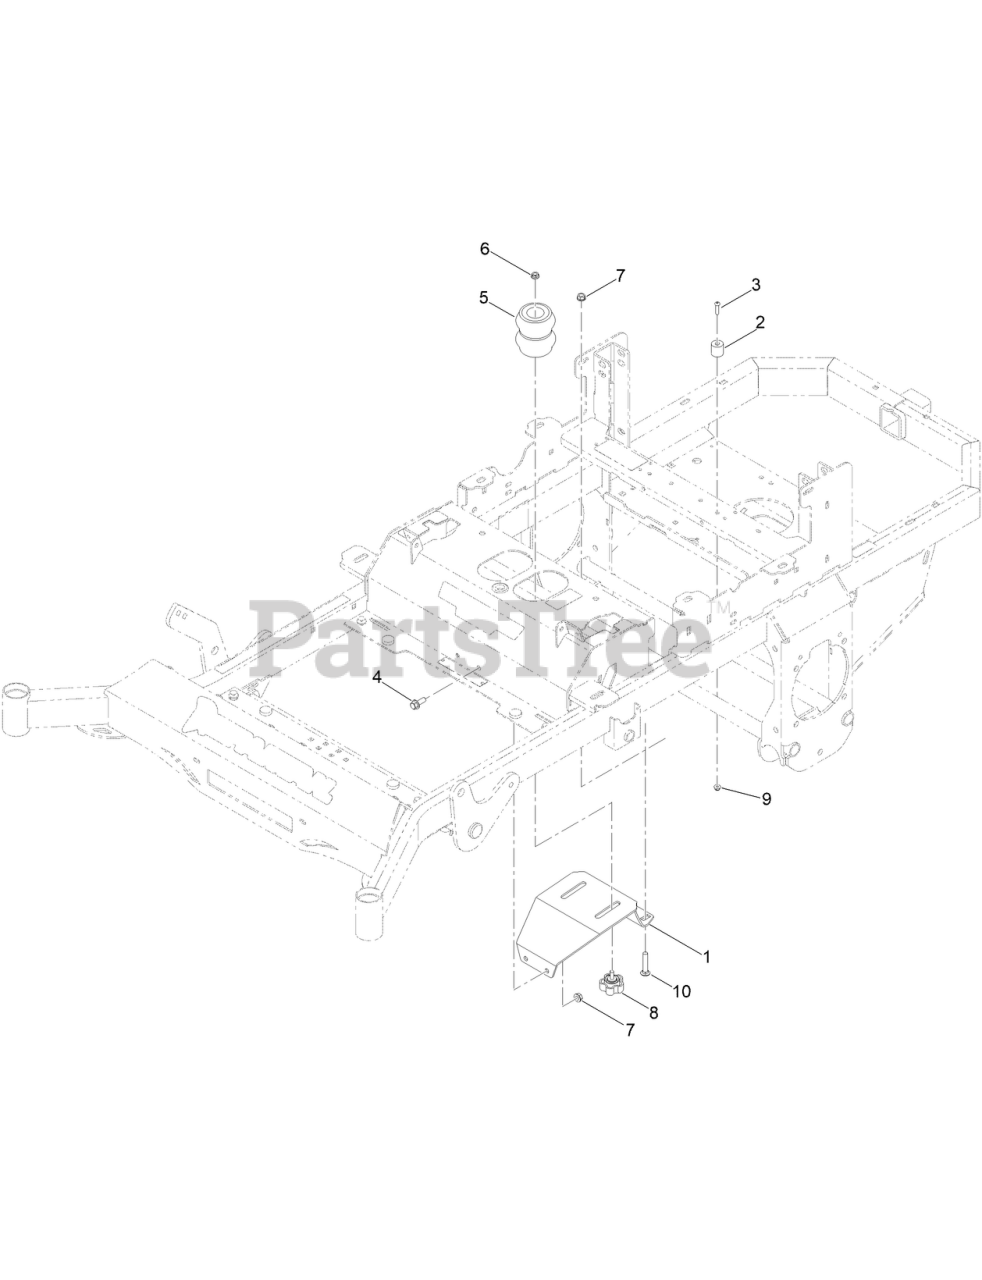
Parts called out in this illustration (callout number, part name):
1	MWR SEAT SUSP BRKT (SRT) PAINTED
2	HOOD REST RUBBER BUMPER
3	1/4-20 X 1 BUTTON SOCKET C/S 18-8 SS
4	SCREW-HHF
5	SRT RR SUSP AND SEAT FT ELASTOMER TCB-3
7	3/8-16 HEX FLANGE NUT W/SERR ZINC YELLOW
8	5/16-18X3/4 SL 5-LOBE MALE KNOB 1.90 DIA
9	NUT-HF
10	SCREW-CARR
